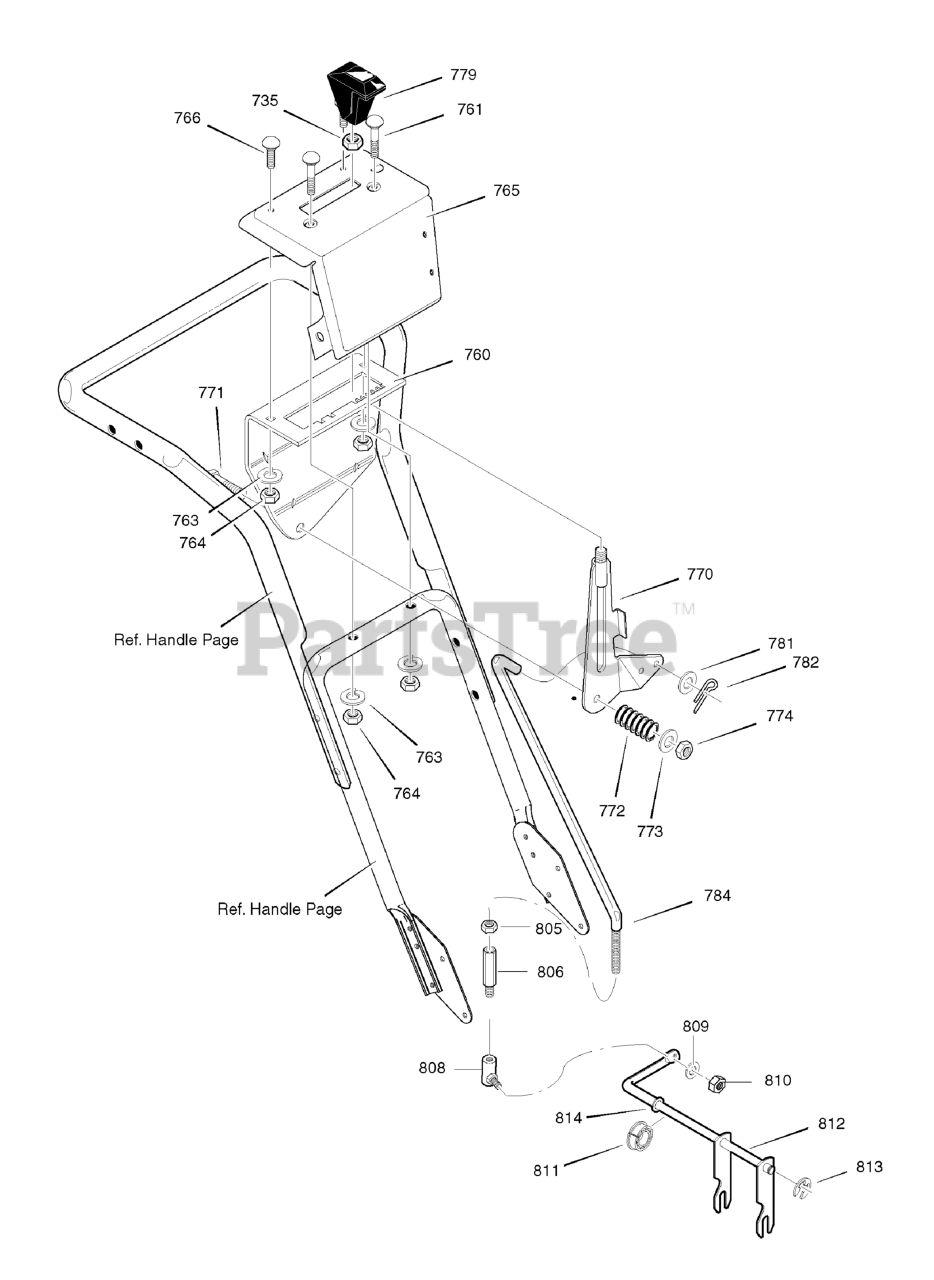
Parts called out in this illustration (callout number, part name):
735	NUT, 3/8-16 HEXJAM
760	BRACKET, SHIFT CONTROL
761	CARRIAGE BOLT, 1/4-20 X 2.00
763	WASHER, SPLIT
764	NUT, 1/4-20 HEX
765	CONTROL PANEL
766	CARRIAGE BOLT, 1/4-20 X .63
770	SHIFT LEVER ASSEMBLY
771	SCREW, 5/16-18 X 1.75
773	FLATWASHER
774	NUT, 5/16-18 NYLON HEX
781	WASHER, FLAT .349 X .69 X .066
782	PIN, COTTER
784	ROD, SPEED CONTROL
805	NUT, 5/16-24
806	ADAPTER, SPEED ROD ASSEMBLY
808	BALLJOINT, STEEL -YZ
809	WASHER
810	NUT, 5/16-24
811	FLANGED BEARING
812	ROD ASSEMBLY, YOKE PANEL
813	RING, RETAINER
